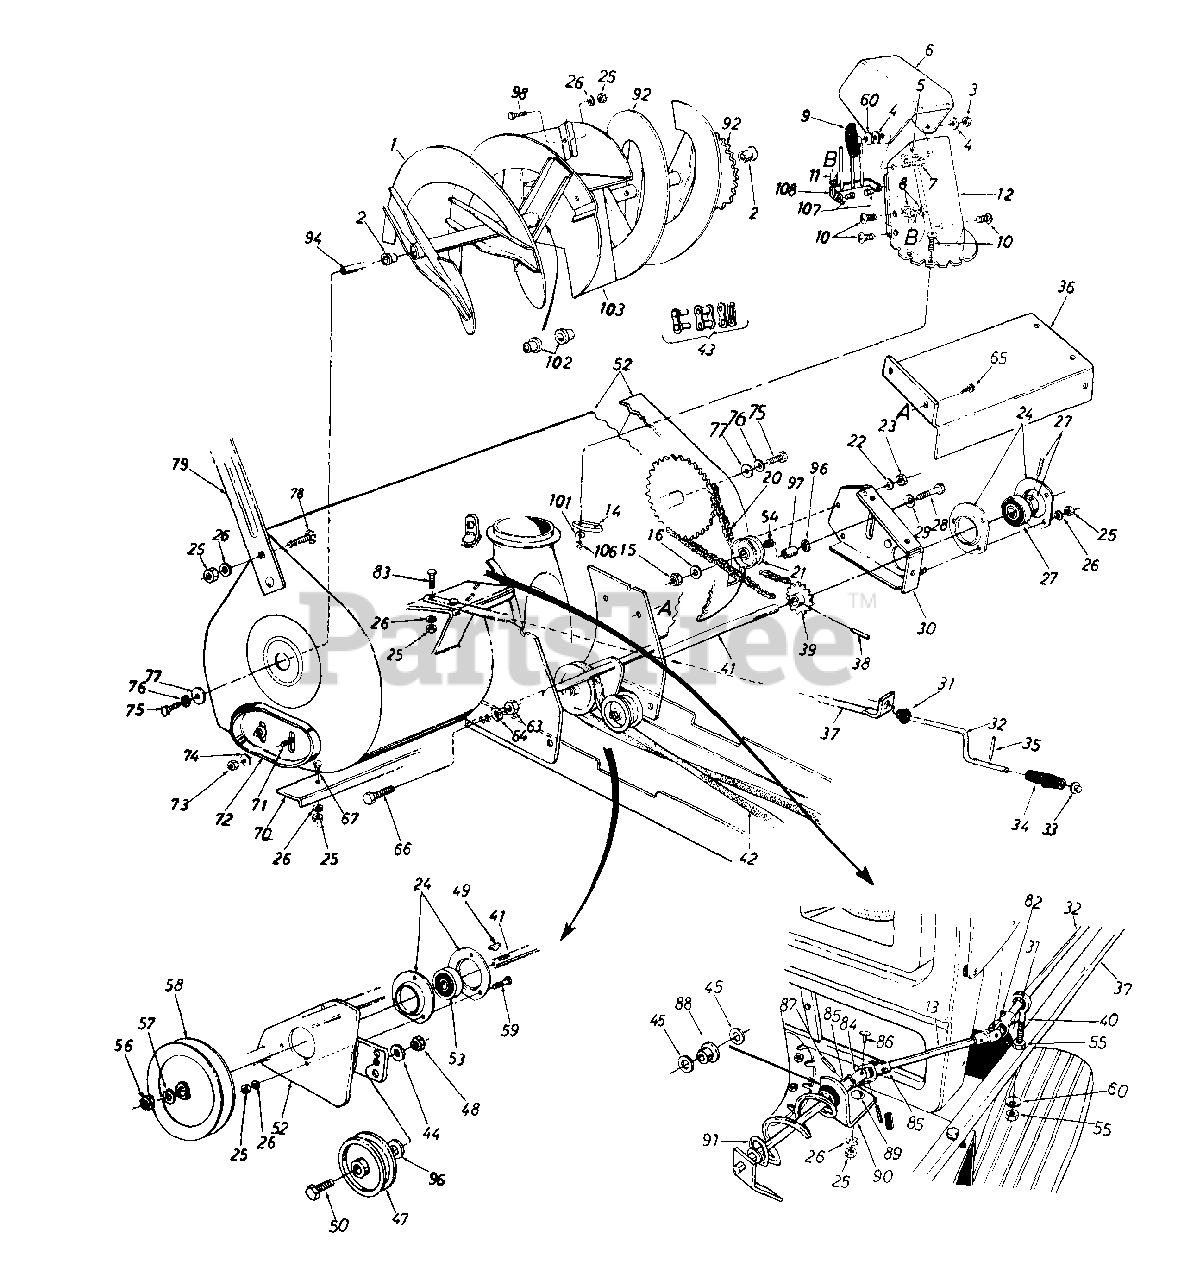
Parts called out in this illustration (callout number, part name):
3	Hex L-Nut 5/16-18 Thd.
4	Fl-Wash. .344" I.D.
5	Truss Mach. Scr. 5/16-18 x .75" Lg.
6	Upper Chute
7	Carriage Bolt 5/16-18 x 1.0" Lg.
8	Hex L-Nut 1/4-20 Thd.
9	Hand Knob
10	Truss Mach. Scr. 1/4-20 x .75" Lg.
11	Ext. Spring
12	Lower Chute
13	Chute Crank Extension Rod
14	Chute Flange Keeper
15	L-Nut 3/8-16 Thd.
20	#420 Chain 1/2" Pitch x 77 Links
21	Plastic Idler 2" O.D.
22	L-Wash. 1/4" I.D.
23	Hex Nut 1/4-20 Thd.
24	Bearing Housing
25	Hex Nut 5/16-18 Thd.
26	L-Wash. 5/16" I.D.
27	Self-Aligning Bearing
28	Hex Bolt 3/8-16 x 1.75" Lg.
29	Belleville Wash. 3/8" I.D.
32	Chute Crank .375" Dia. x 34.5" Lg.
33	Push Nut 3/8" Rod
35	Roll Pin
39	14 Teeth Sprocket Ass'y.
40	Eyebolt 5/16-18 x 3.0" Lg.
42	"V"-Belt
43	Master Link for #420 Chain
44	L-Wash. 3/8" I.D.
45	Fl-Wash. .385" I.D. x .62" O.D.
47	Fl-Idler with Flanges
48	Hex Jam L-Nut 3/8-16 Thd.
49	#61 Hi-Pro Key 3/16 x 5/8 Dia.
50	Hex Bolt 3/8-16 x 1.75" Lg.
52	Spiral Housing Ass'y.
53	Self-Aligning Bearing
54	Sleeve Bearing .50" I.D.
55	Hex Nut 5/16-18 Thd.
56	Hex Nut 3/4-10 Thd.
57	L-Wash. 3/4" I.D.
58	"V"-Pulley .750" I.D. x 6" O.D.
59	Hex Sems Bolt 5/16-18 x .75" Lg
60	Bell-Wash. .345" I.D. x .88" O.D.
63	Hex L-Nut 1/2-20 Thd.
64	L-Wash. 1/2" I.D.
65	Hex Self-Tap Scr. 1/4-20 x .5" Lg.
66	Hex Bolt 1/2-20 x 1.25" Lg.
67	Carriage Bolt 5/16-18 x .75"
72	Skid Shoe
73	Hex Jam Nut 3/8-16 Thd.
74	Belleville Wash. 3/8" I.D.
75	Hex Bolt 1/2-13 x 1.25" Lg.
76	Belleville Wash. 1/2" I.D.
78	Carriage Bolt 5/16-19 x .62" Lg.
83	Hex Bolt 5/16-18 x 1.5" Lg.
85	Joint Bracket Ass'y.
86	Oval Head Rivet
87	Spring Pin Roll 1/8" Dia. x .75" Lg.
88	Nylon Bushing
89	Carriage Bolt 5/16-18 x .75" Lg.
90	Chute Crank Bracket
91	Chute Crank Ass'y.
97	Idler Spacer
98	Carriage Bolt 5/16-18 x .75" Lg.
101	Fl-Wash. 1/4" I.D.
102	Plastic Bushing
107	Shld. Nut 1/4-20 Thd.
